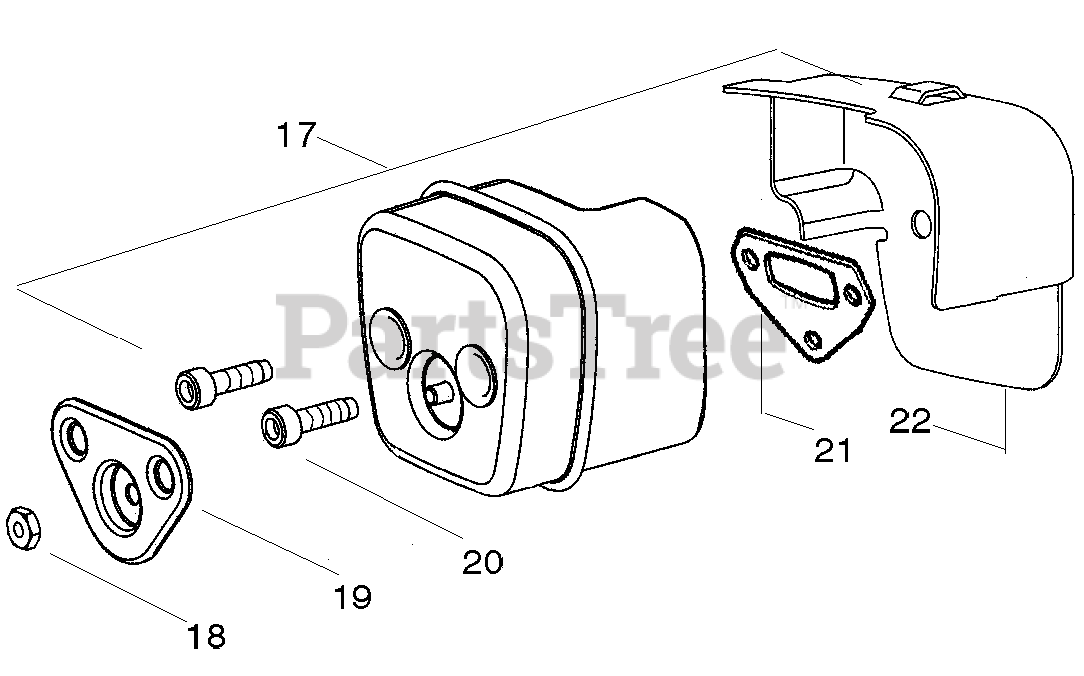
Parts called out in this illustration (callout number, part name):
17	MUFFLER KIT
18	NUT-BRASS
19	COVER BOLT
20	SCREW MUFFLER
21	GASKET-MUFFLER
22	BACKPLATE, MUFFLER
